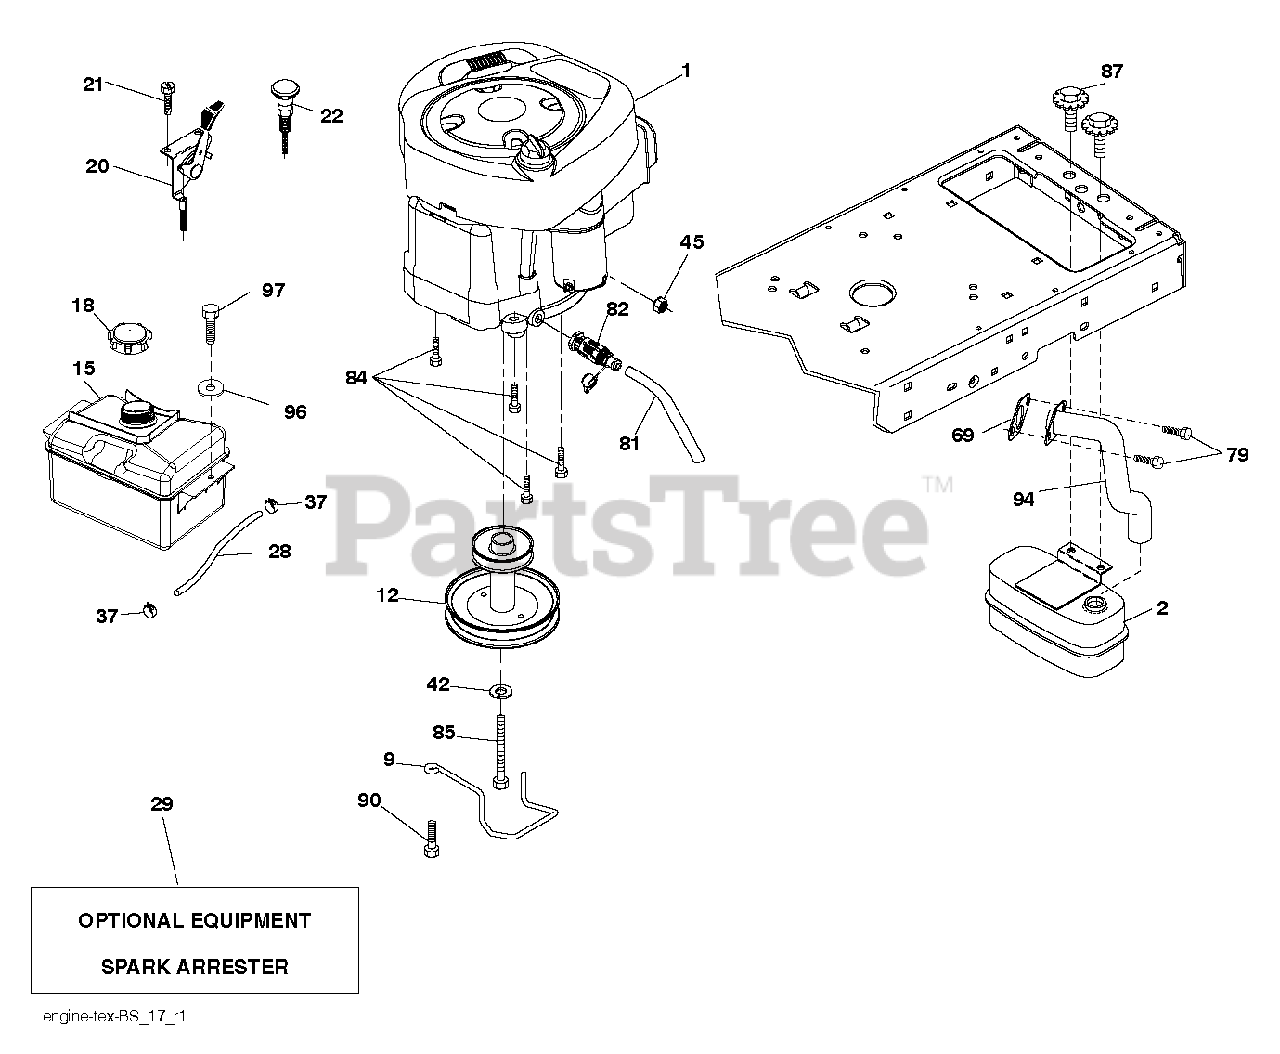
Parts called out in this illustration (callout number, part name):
2	MUFFLER.SINGLE.CYL.KOHL/B&S
9	KEEPER.BELT.ENGINE.4.2
12	PULLY ENGINE
15	TANK FUEL FRT 1.5 GAL
18	CAP ASM.FUEL.2.25"FR.
20	CONTROL.TH/CK.C.
21	SCREW.#10 X 0.750.BOS THREAD
28	LINE.FUEL.20
29	ARRESTER SPARK (OPTIONAL)
37	HOSE CLAMP
42	LOCKWASHER
45	NUT
69	REPL BY 532 27 22-93
79	SCREW.SOCKET HD.5/16-1
81	TUBE, DRAIN OIL ASM.
82	VALUE.OIL.DRAIN
84	SCREW.3/8-16
85	BOLT HEX 7/16-20X4-1/4"
87	BOLT, 5/16-18 X 1 3/4
90	SCREW 3/8-16X1
94	EXHAUST.TUBE.B&S.
97	SCREW HEXWSHR 1/4-20X3/4
